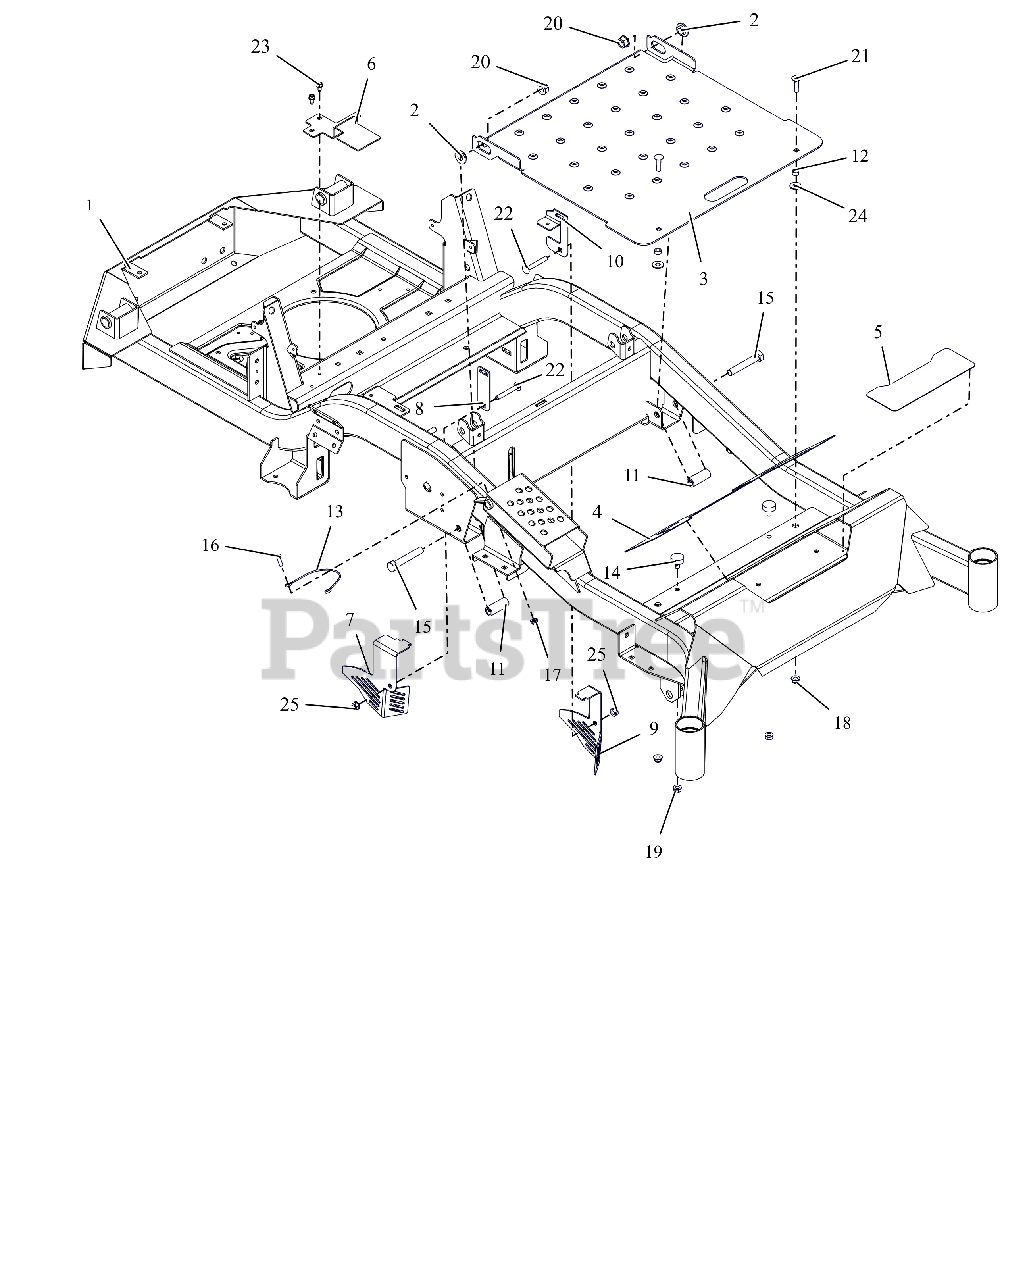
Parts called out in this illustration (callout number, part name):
1	APEX,44-52 FRAME W/SAFETY DECA
2	BSHG-FLG .515X.750X.395X1.120
3	PANEL, ACCESS
4	GRIP, FRONT
5	GRIP, STEP
6	GUARD, TRANSAXLE FAN RH (BLACK)
7	GUARD, TRANSAXLE FAN - RH
8	BRKT, TRANSAXLE FAN GUARD
9	BRKT, TRANSAXLE FAN GUARD-LH
10	MOUNT, TRANSAXLE GUARD
11	SPACER, .515X.75X1.83
12	BSHG-SLV .344 X .500 X .260
13	CABLE, 12.0 LANYARD, NYLON
14	BUMPER, RUBBER
15	BLT, HEX .50-13X3.00 G5 ZCC
16	BLT, HEX .25-20X.75 G5 ZCC
17	NUT,NYL-FLG .25-20 GF ZCC
18	NUT,LK-NYL-FLG .31-18 G5ZC120
19	NUT,SPNLK-FLG .31-18 G5 ZCC
20	NUT-LK-TOP-FLG .500-13 GF ZCC
21	BLT, RHSSN.31-18X1.25 G5 ZCC
22	BLT, RHSSN.31-18X2.25 G5 ZCC
23	SCR-TAP .25-20X.50 HWH ZCC
24	WSHR,FLT .375X.875X.083 ZCC
25	NUT,LK-CTR-FLG .31-18 GF ZCC
